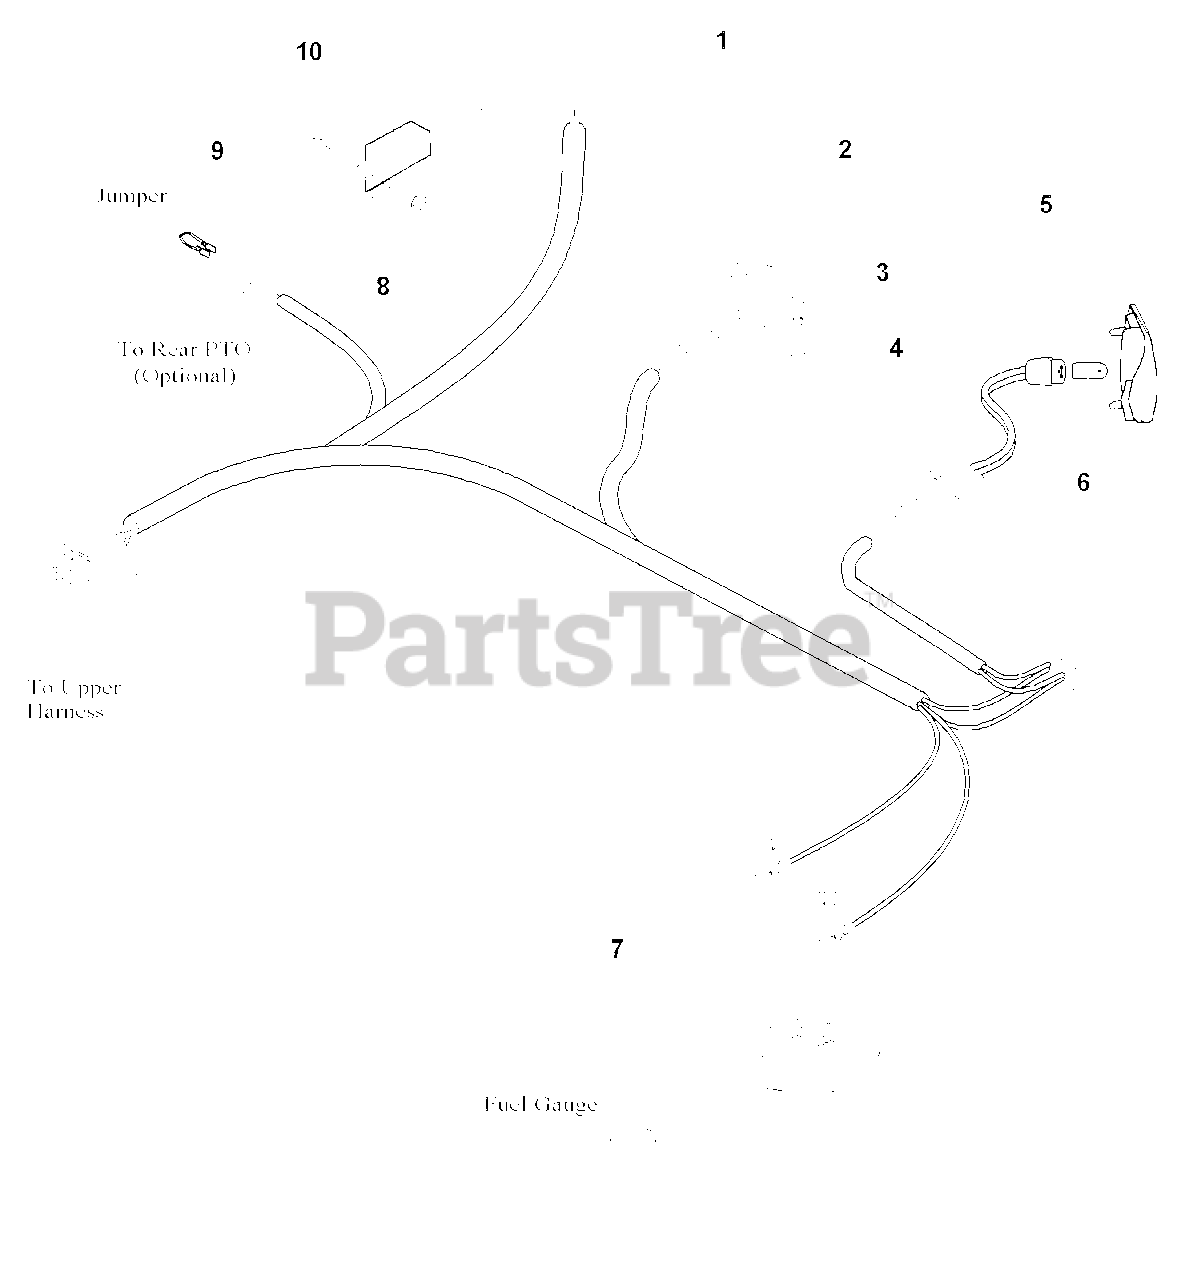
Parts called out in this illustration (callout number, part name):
1	HARNESS, Rear (Models with Kohler Engines)
1	HARNESS, Rear (Models with Kawasaki Engines)
2	SWITCH, Seat (Normally Open - Models with Kawasaki Engines) - Gray
2	SWITCH, Seat (Normally Closed - Models with Kohler Engines) - Black
3	LOCKWASHER, 1/4
4	CAPSCREW, 1/4-20 x 3/4
5	TAIL LIGHT, Assembly (Includes Bulb)
6	BULB, Tail Light
7	NUT, Hex Flange, #10-32
8	NUT, KEPS Lock, #10-24
9	CAPSCREW, #10-24 x 5/8
10	SWITCH, Cruise
